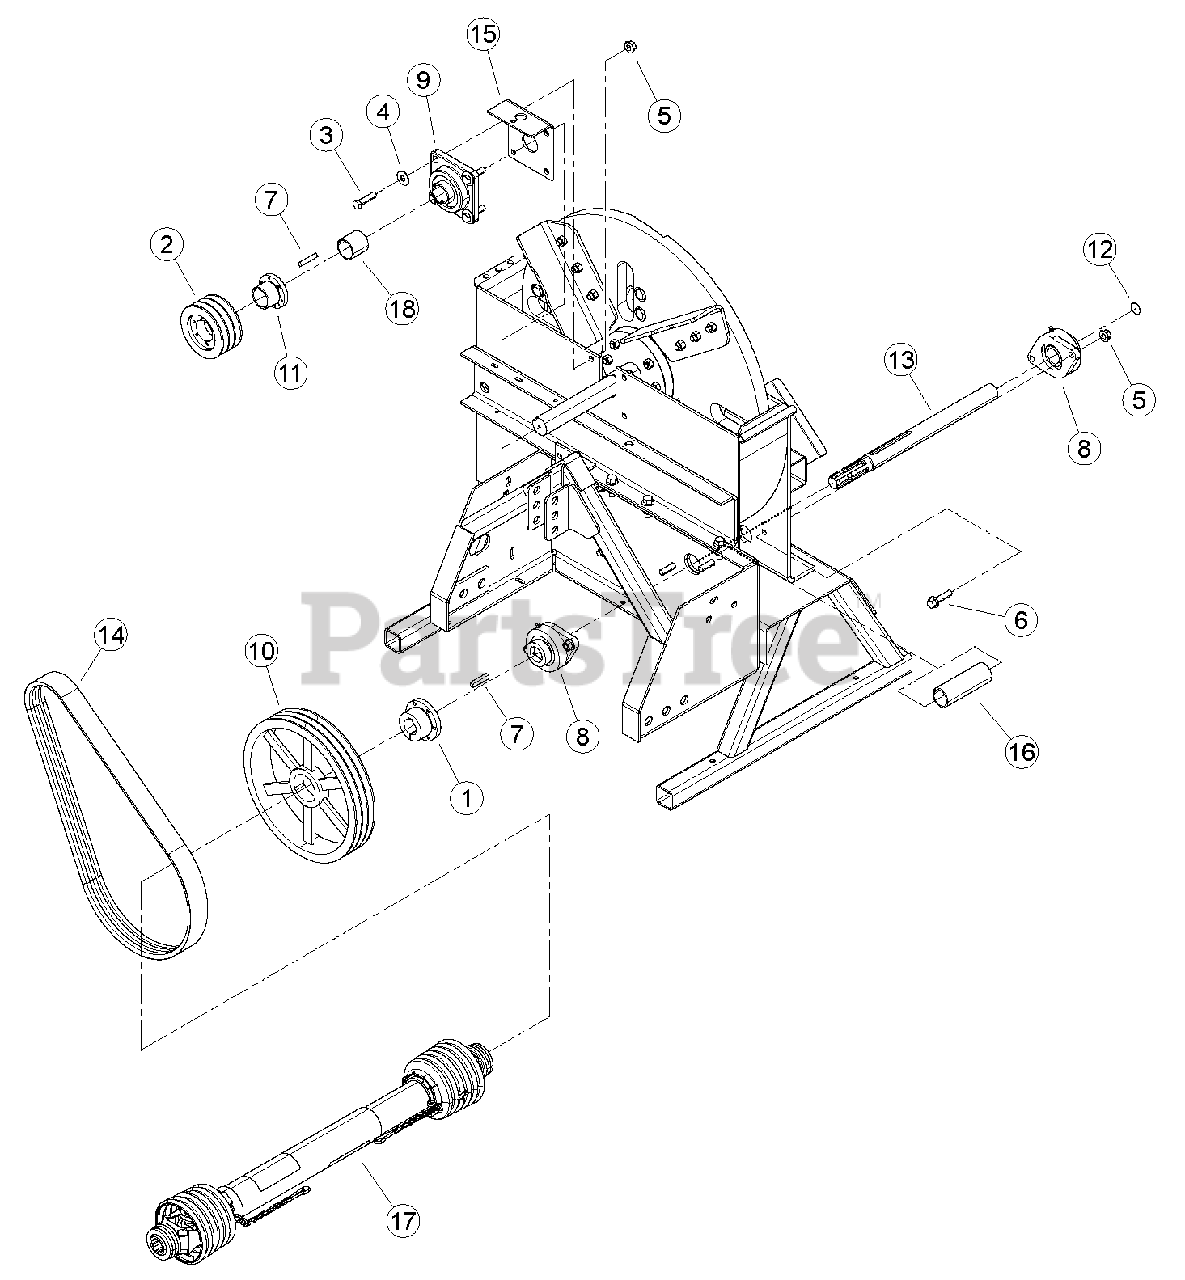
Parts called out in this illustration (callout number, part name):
1	BUSHING, SK 1-1/2"
2	SHEAVE, 3B4.8 SD
3	BOLT, 1/2 X 2 GR5 HEX CAPSCREW ZP
4	WASHER, 1/2" FLAT ZP
5	NUT, 1/2-13 NYLOCK FLANGE
6	BOLT, 1/2-13 X 2 HWH GR5 CZP
7	KEY, 3/8" SQ X 2" LG PLAIN
8	BEARING, 2 BOLT FLANGE 1-1/2" BORE
9	BEARING, 1-3/4 4 BOLT FLANGE
10	SHEAVE, 3B13.6 SK
11	BUSHING, SD 1-3/4"
12	DECAL, ROTATING SHAFT
13	SHAFT, 6 SPLINE INPUT
14	BELT, 3RB64
15	WELDMENT, LEFT BEARING BRACKET
16	SHIELD, SHAFT
17	ASSEMBLY, 8" & 9" PTO DRIVELINE
18	SPACER, 2.0 X 1.88
